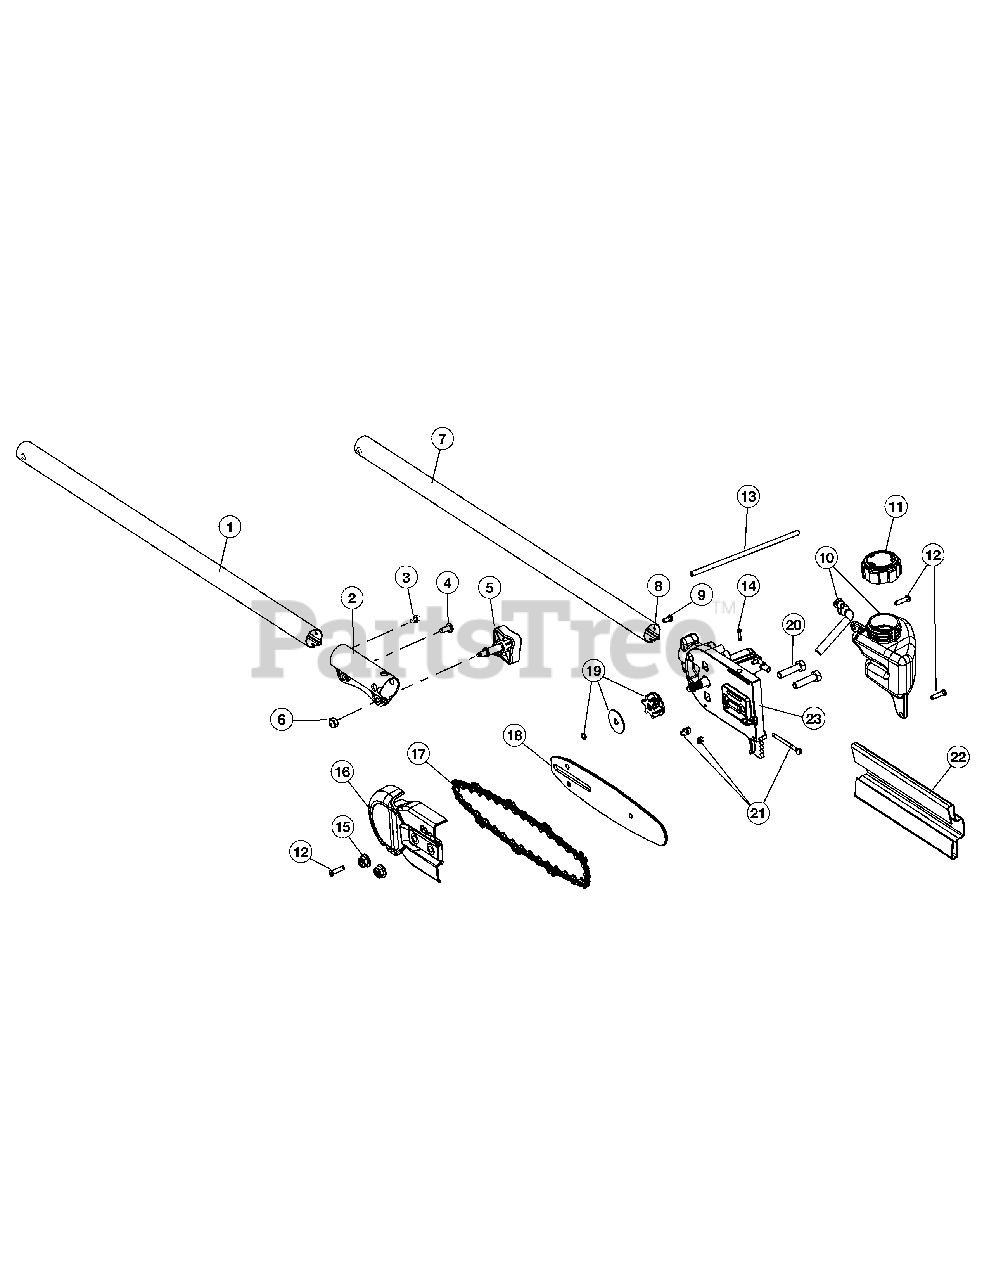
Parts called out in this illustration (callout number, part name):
1	Extension Boom
2	Split Boom Coupler (includes 3-6)
5	Adjustment Knob
6	Knob Retaining Nut
7	Drive Shaft Housing (includes 8)
8	Flexible Drive Shaft
9	Screw
10	Oil Tank Assembly
11	Fuel Cap Assembly
13	Oil Line
16	Chain Guard
19	Sprocket Assembly
21	Chain Tension Hardware Assembly
22	Chain Cover
23	Gearbox Assembly (includes 14 & 19)
